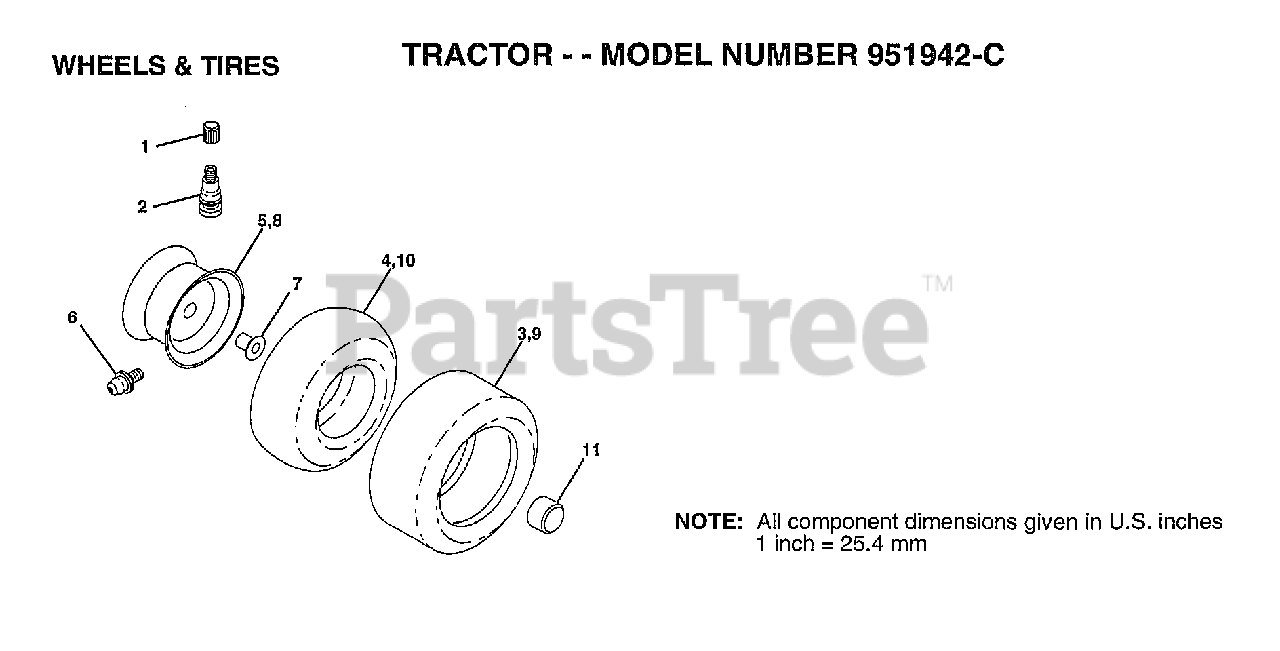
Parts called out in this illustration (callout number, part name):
1	VALVE CAP
2	VALVE STEM LT
4	TUBE.16X6.5/7.5-8
5	RIM.FRONT.
6	FITTING LT
6	ZERK FITTING M
7	"FLANGE, BEARING"
8	"WHEEL,REAR"
10	TUBE.23X8/10-12
11	HUB CAP
